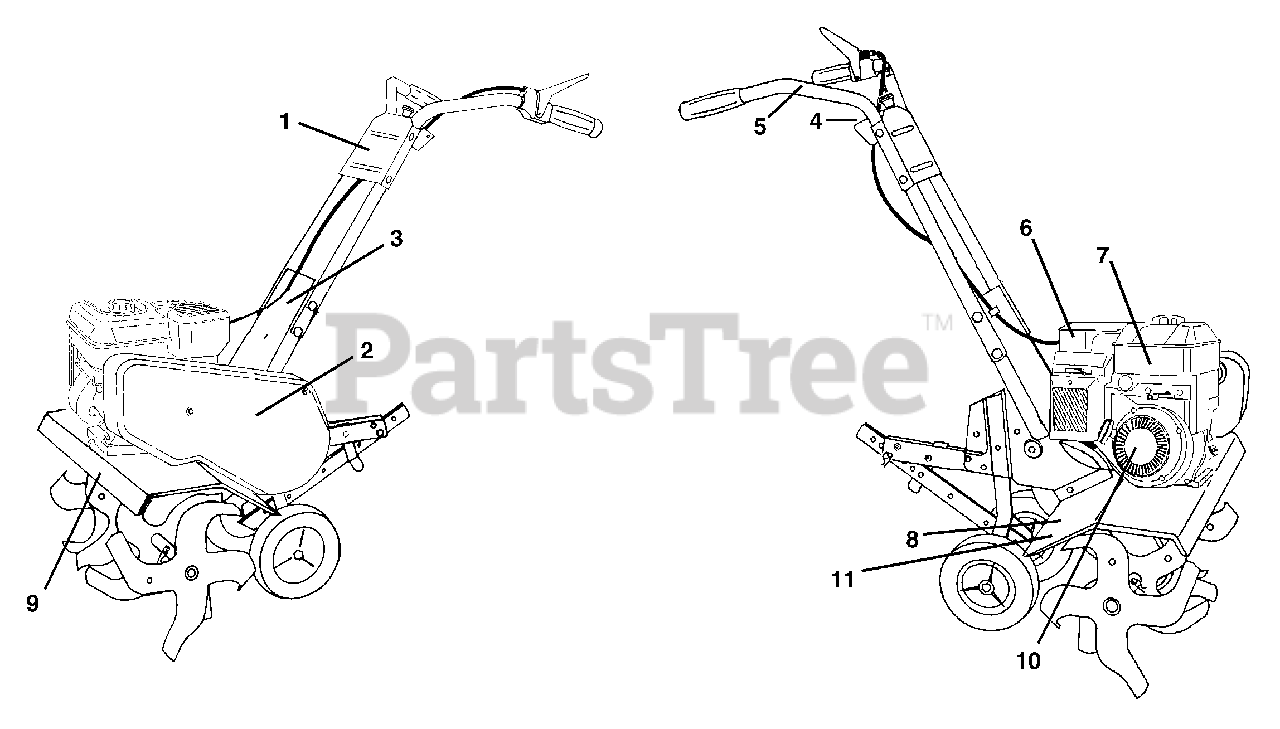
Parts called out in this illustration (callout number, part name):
1	Decal, Logo
2	Decal, Logo
3	Decal, HP, Reverse
4	Decal, Reverse, Tine Control
5	Decal, Hand Placement
6	Decal, Eng. Tiller
7	Decal, OHV. N-I/C
8	Decal, Warning, Rotating Tines
9	Decal, Hvy Duty
10	Decal, Rewind Intek
11	Decal, Tine Shield Wrng. Dom
